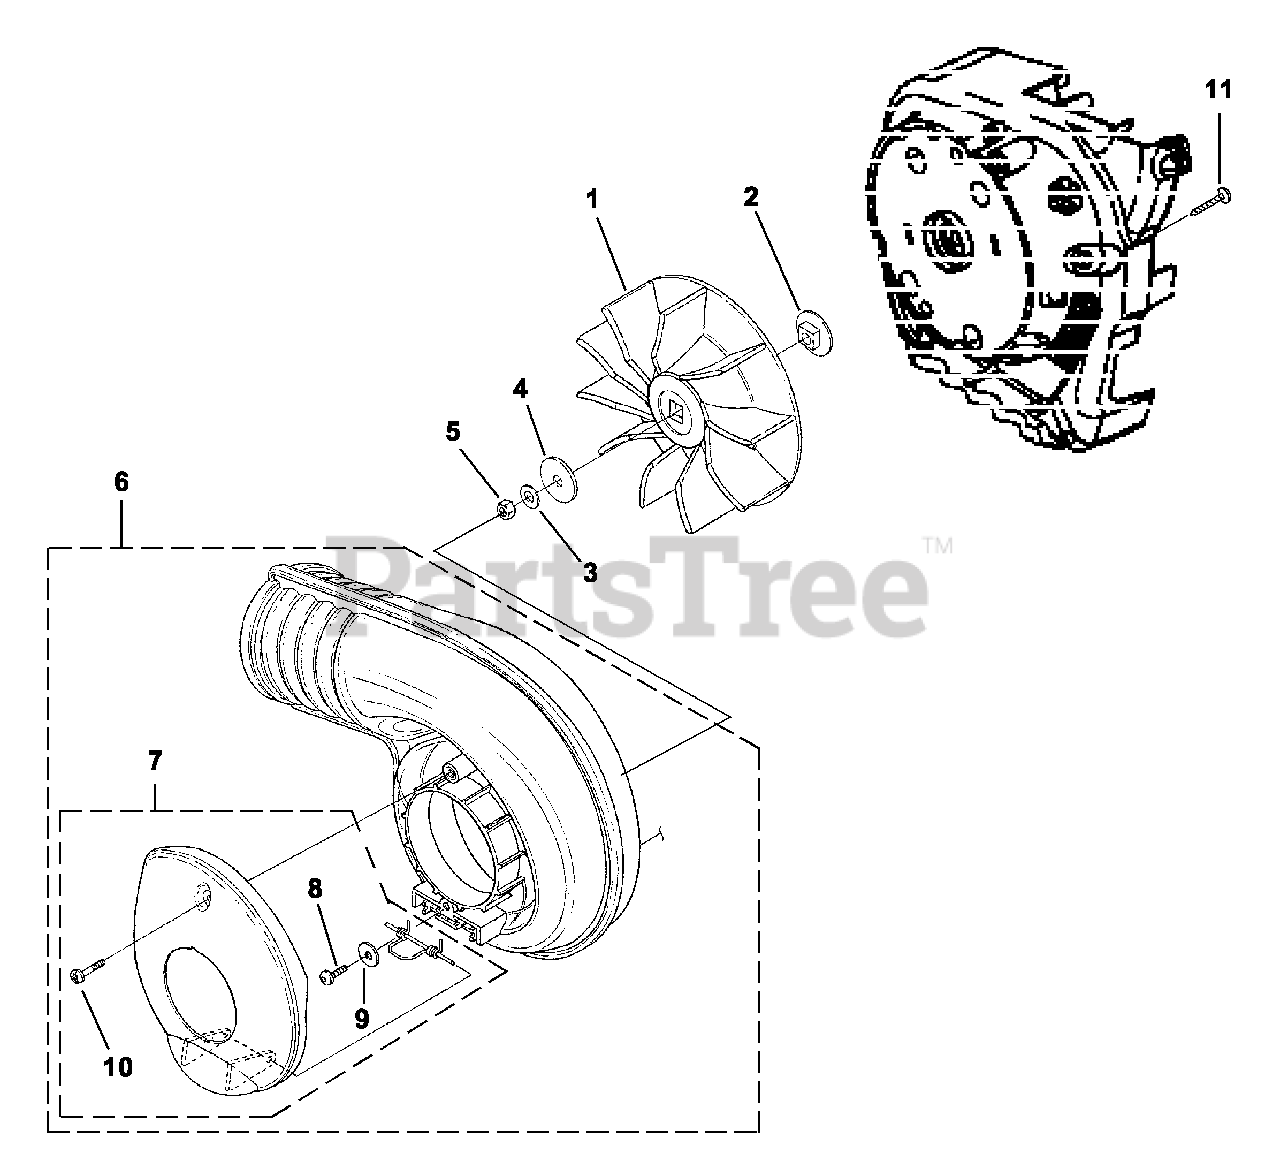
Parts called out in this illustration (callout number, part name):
1	Fan
2	Adapter, Fan
3	Washer, Belleville
4	Washer, Flat
5	Nut (3/8-24)
6	Volute W/Door Assembly
7	Volute Door
8	Screw, Thread Forming (10-14 X 1/2)
9	Washer
10	Screw, Machine (10-24 X 3/4)
11	Screw, Plastite (10-14 X 7/8)
